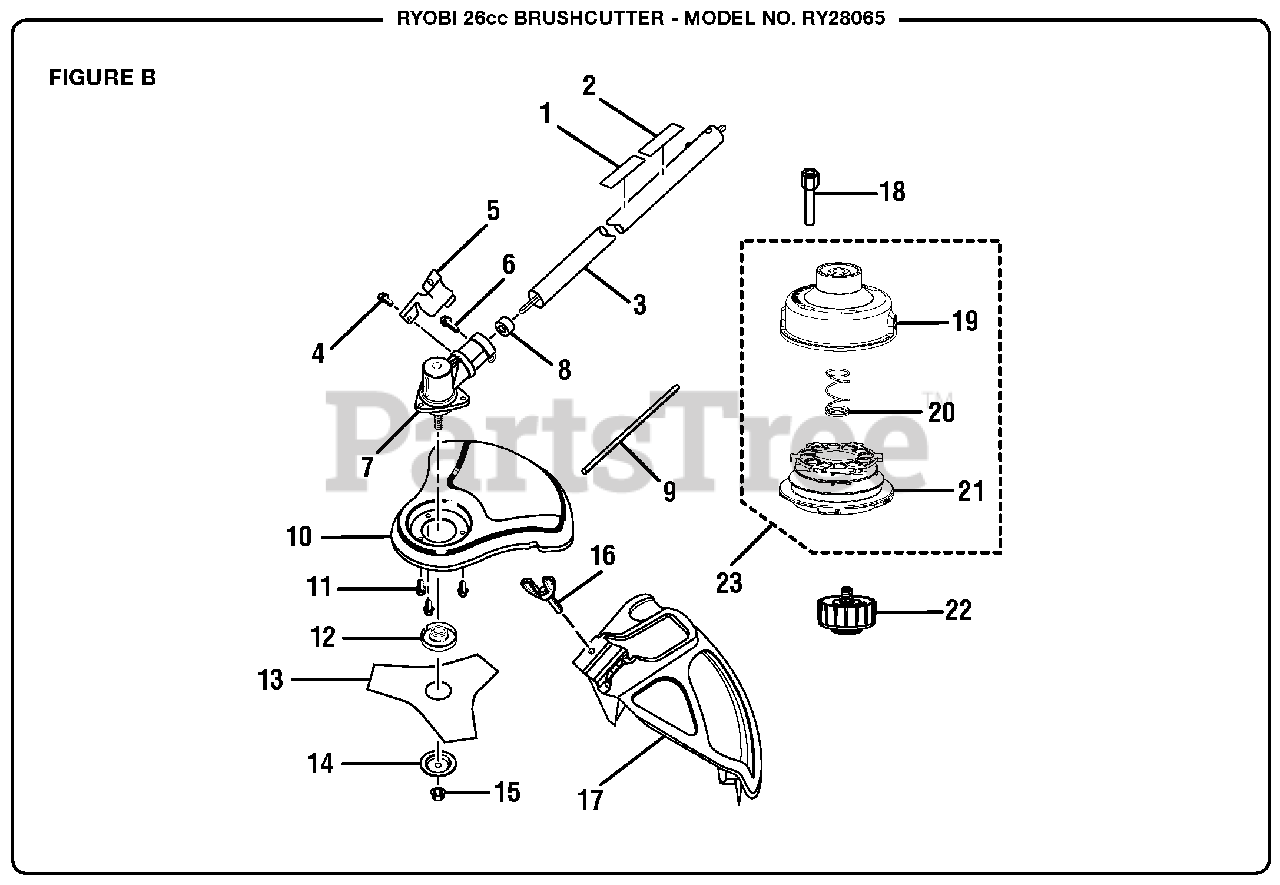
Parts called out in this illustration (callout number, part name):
1	Expand-it Label
2	Brushcutter Safety Label
3	Straight Shaft Assembly
4	Screw (10-24 x 5/8 in.)
5	Clamp
6	Screw (1/4-20 x 1-1/4 in.)
7	Gear Head
9	Gear Head Locking Tool
10	Brushcutter Guard
11	Screw (10-24 x 1/2 in.)
12	Flanged Washer
14	Cupped Washer
15	Blade Nut
16	Screw (1/4-20 x 1-1/4 in.)
17	Grass Deflector Assembly
19	String Head Housing
20	Spring
21	Spool
22	Spool Retainer
23	String Head Assembly
